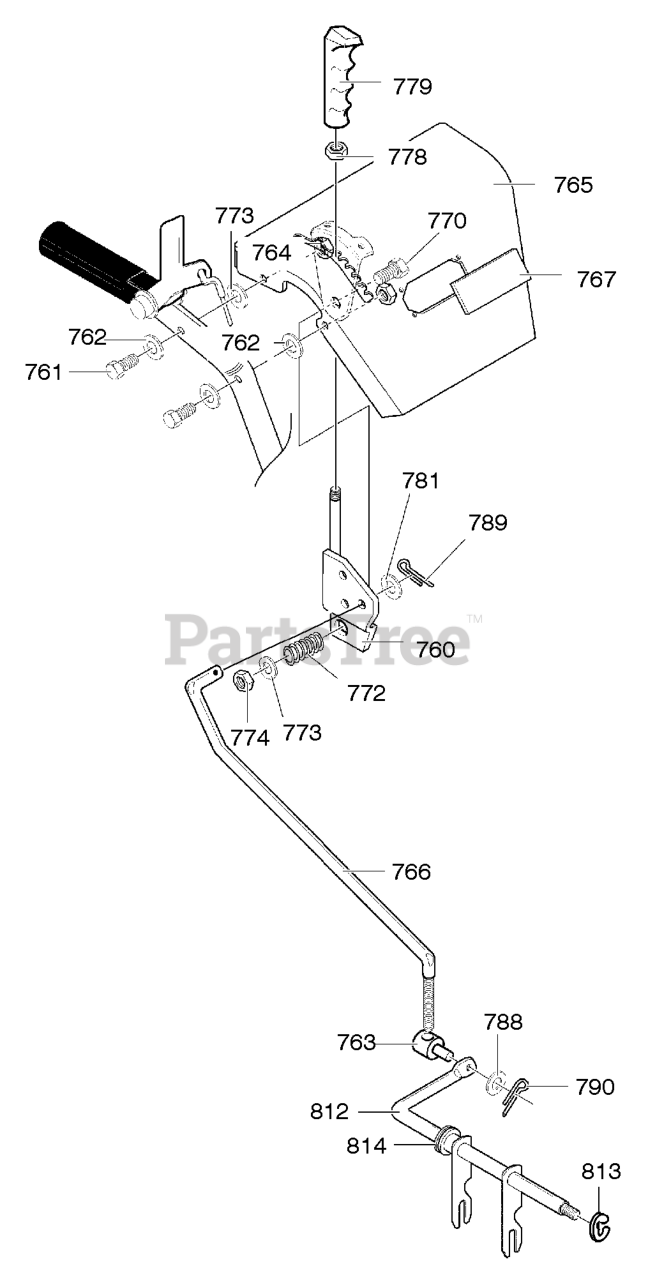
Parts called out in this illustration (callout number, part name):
760	HANDLE ASSY SPD CTRL
761	SCREW, 5/16-18 x 1.75
763	NUT, TRUNNION
764	NUT, 5/16-18 HEXWDFLLK
765	ASSY. BAY LT
766	ROD, SPEED CONTROL
767	PLATE, BLANKING LIGHT
770	SCREW 3/8-16X2.00
773	FLATWASHER
774	NUT, 3/8-16 HEXNYL
778	NUT, 3/8-16 REGHEX
779	HANDLE 3/8-16
781	FLATWASHER
788	FLATWASHER
789	PIN, COTTER
790	COTTER PIN
812	ROD, ASSY YOKE
813	RING, RETAINER
814	BEARING, FLANGE
